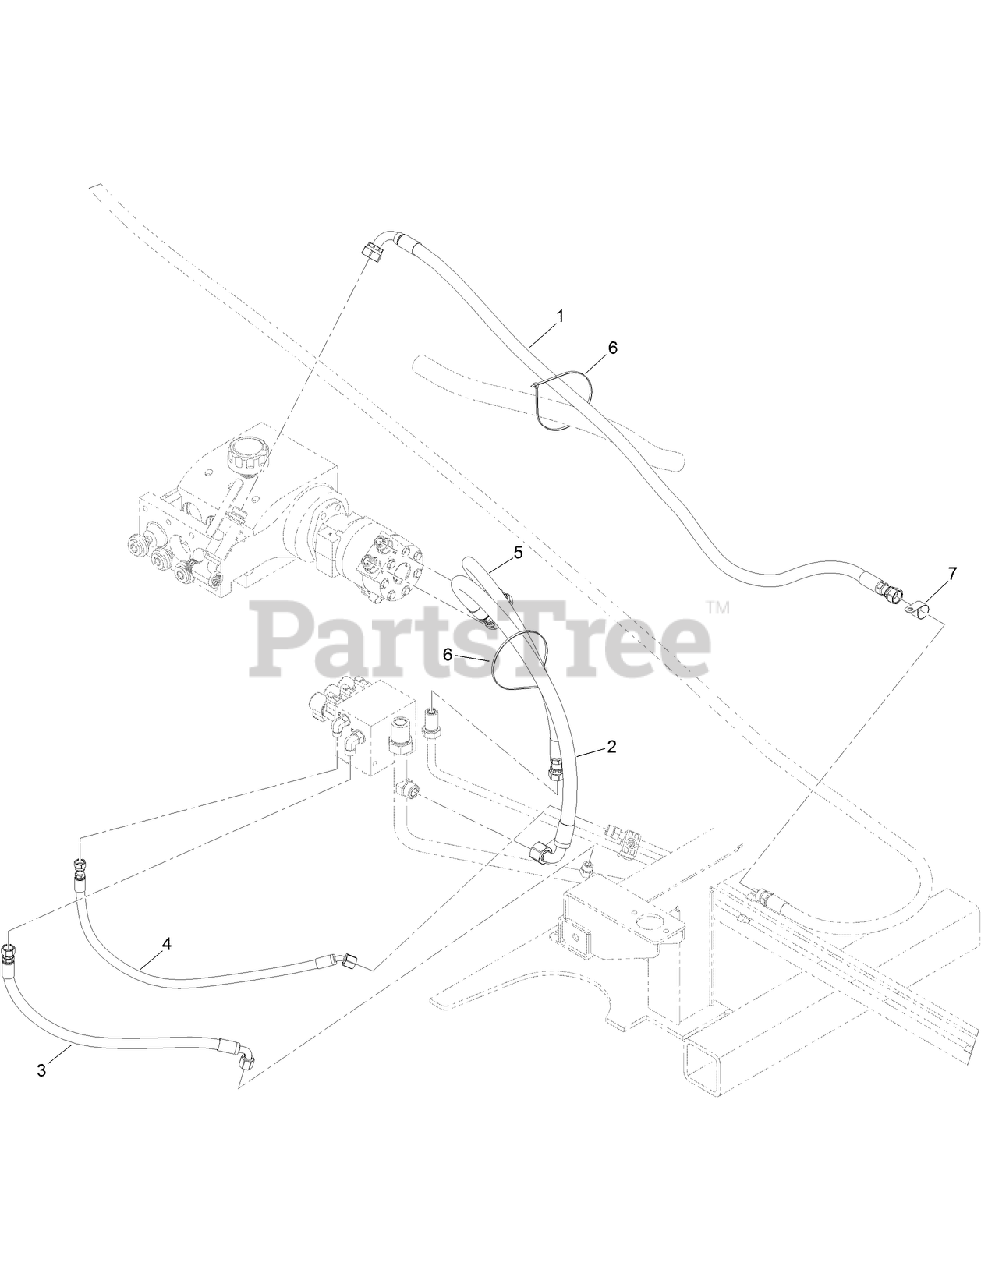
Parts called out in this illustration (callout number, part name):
1	HOSE-ASM-HYD
2	HOSE ASM-HYD
3	HOSE ASM-HYD
4	HOSE ASM-HYD
5	HOSE ASM-HYD
6	TIE-CABLE
7	R-CLAMP
